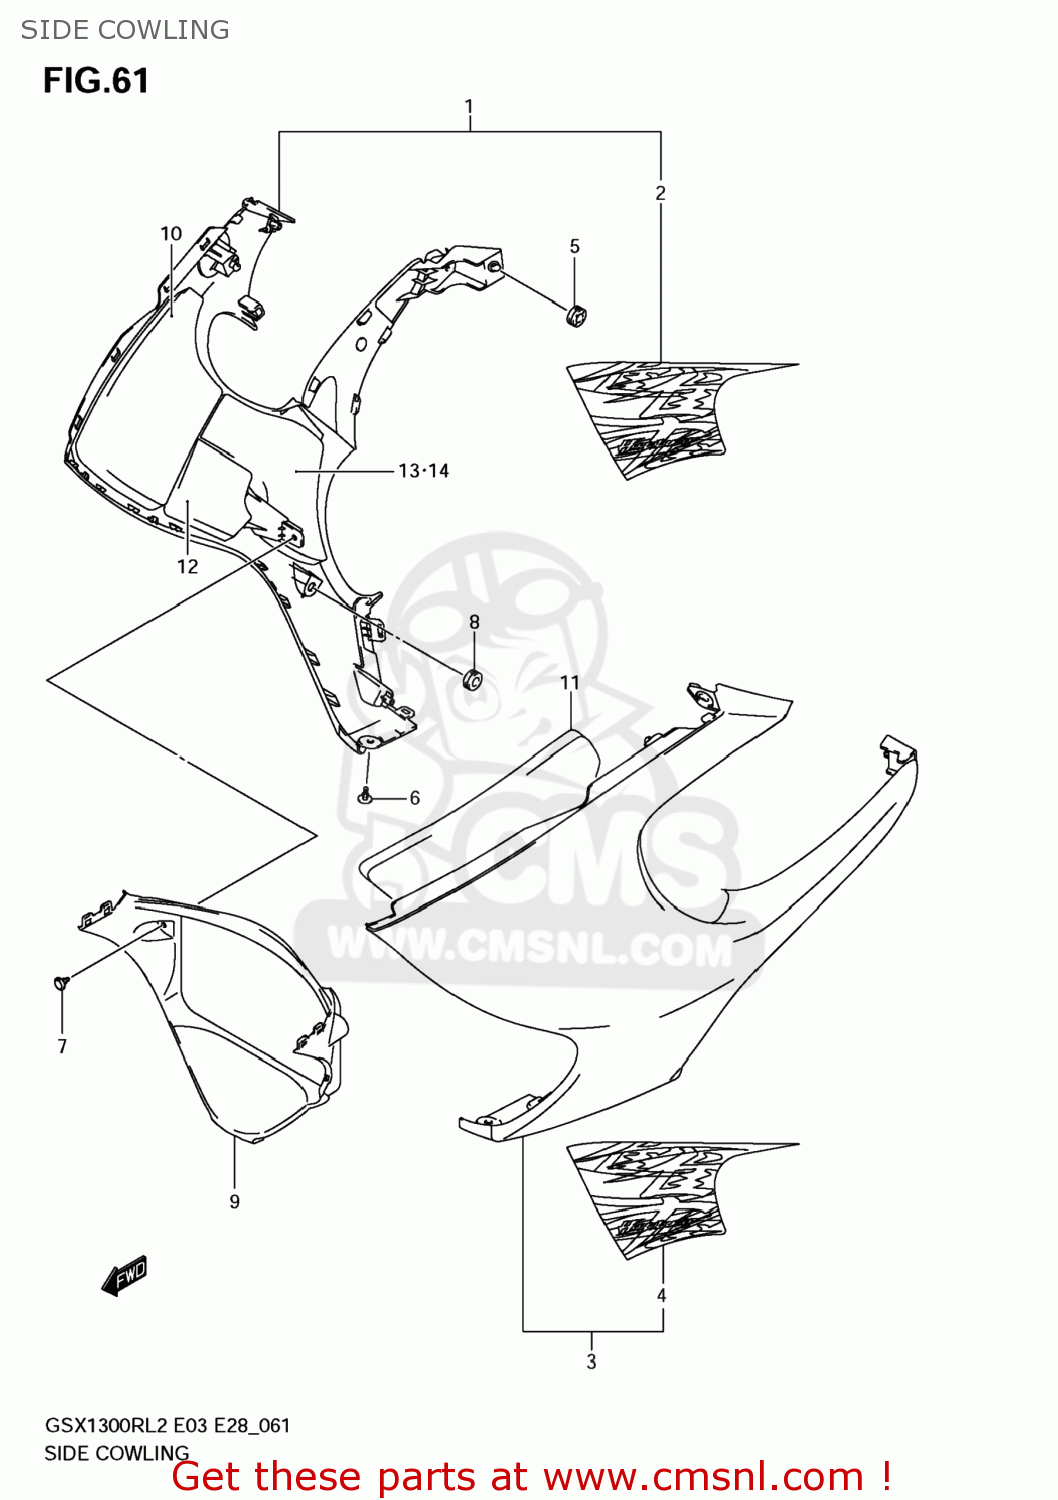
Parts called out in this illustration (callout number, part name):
1	COWLING,SIDE,R(RED)
2	TAPE,SIDE COWLING,R
3	COWLING,SIDE,L(RED)
4	TAPE,SIDE COWLING,L
5	CUSHION
6	CLIP
7	CLIP
8	CUSHION
9	COWLING,UNDER CTR
10	CUSHION,SIDE COWL,R
11	CUSHION,SIDE COWL,L
12	CUSHION,SIDE COWL
13	SHIELD,SIDE COWL,R
14	SHIELD,SIDE COWL,L
